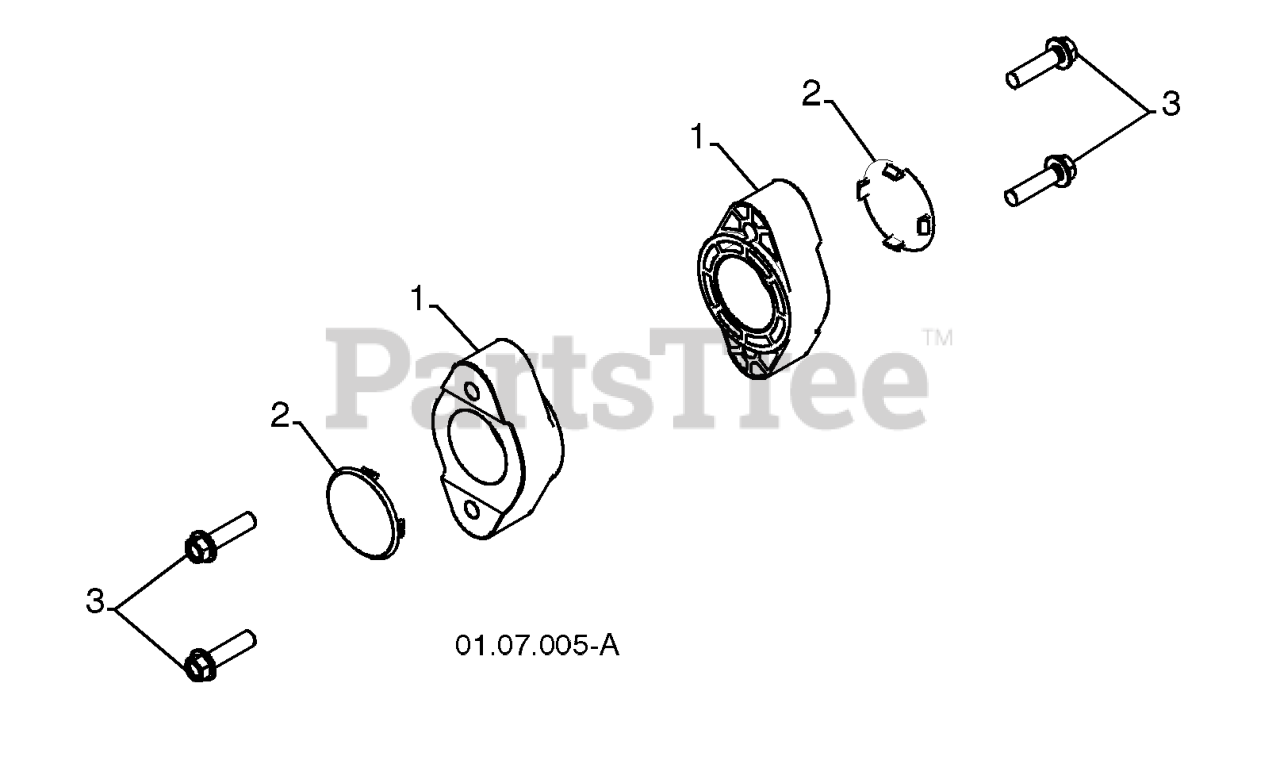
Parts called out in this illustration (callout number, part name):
1	BEARING, AUGER
2	PLUG.BEARING.HOLE.HSG
3	SCREW, HEX HD 5/16X1
